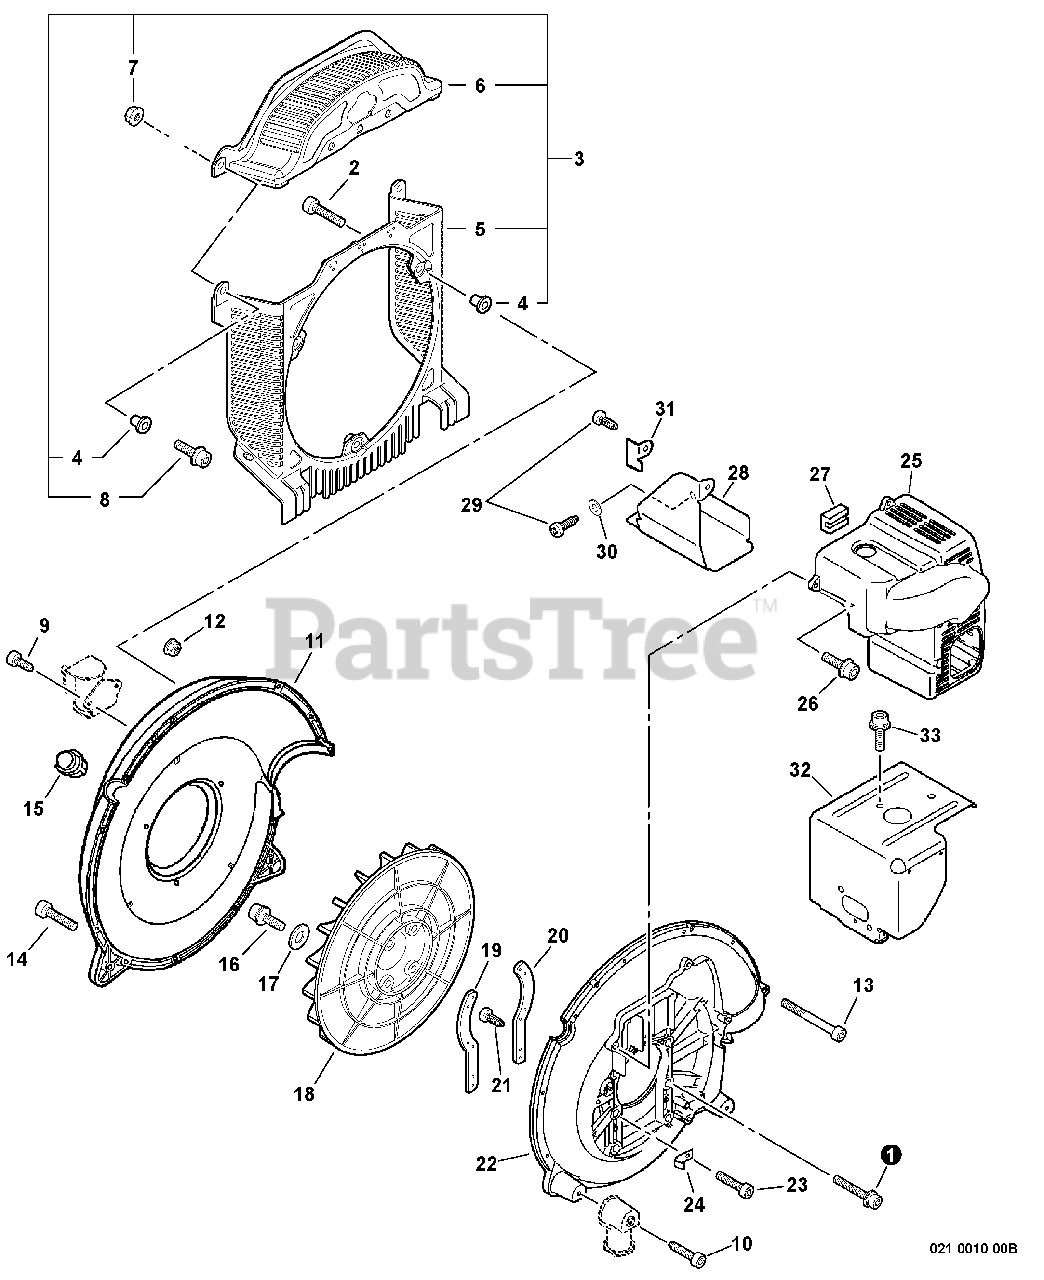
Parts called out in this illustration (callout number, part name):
1	SCREW 6×35
2	SCREW TAPPING 5×20
3	GUARD KIT, DEBRIS
5	SHIELD, DEBRIS - LOWER
6	SHIELD, DEBRIS - UPPER
7	NUT, LOCK M5
8	BOLT 5×20
9	SCREW TAPPING 5×16
10	SCREW TAPPING 5×16
11	COVER, FAN
12	NUT, FLANGE M5
13	BOLT 5×60
14	SCREW TAPPING 5×20
15	PLUG, FAN CASE
16	BOLT 6×35
18	FAN, BLOWER
19	PLATE, ENGINE
20	PLATE, ENGINE
21	SCREW 5×14
22	COVER, FAN - OUTER
23	SCREW TAPPING 5×16
25	COVER, ENGINE
26	SCREW TAPPING 5×20
27	CUSHION
28	INSULATOR, MUFFLER
29	SCREW 5×10
30	WASHER 5.5×12×0.8
31	PLATE, ANGLE
32	COVER, CYLINDER
33	SCREW 6×35
